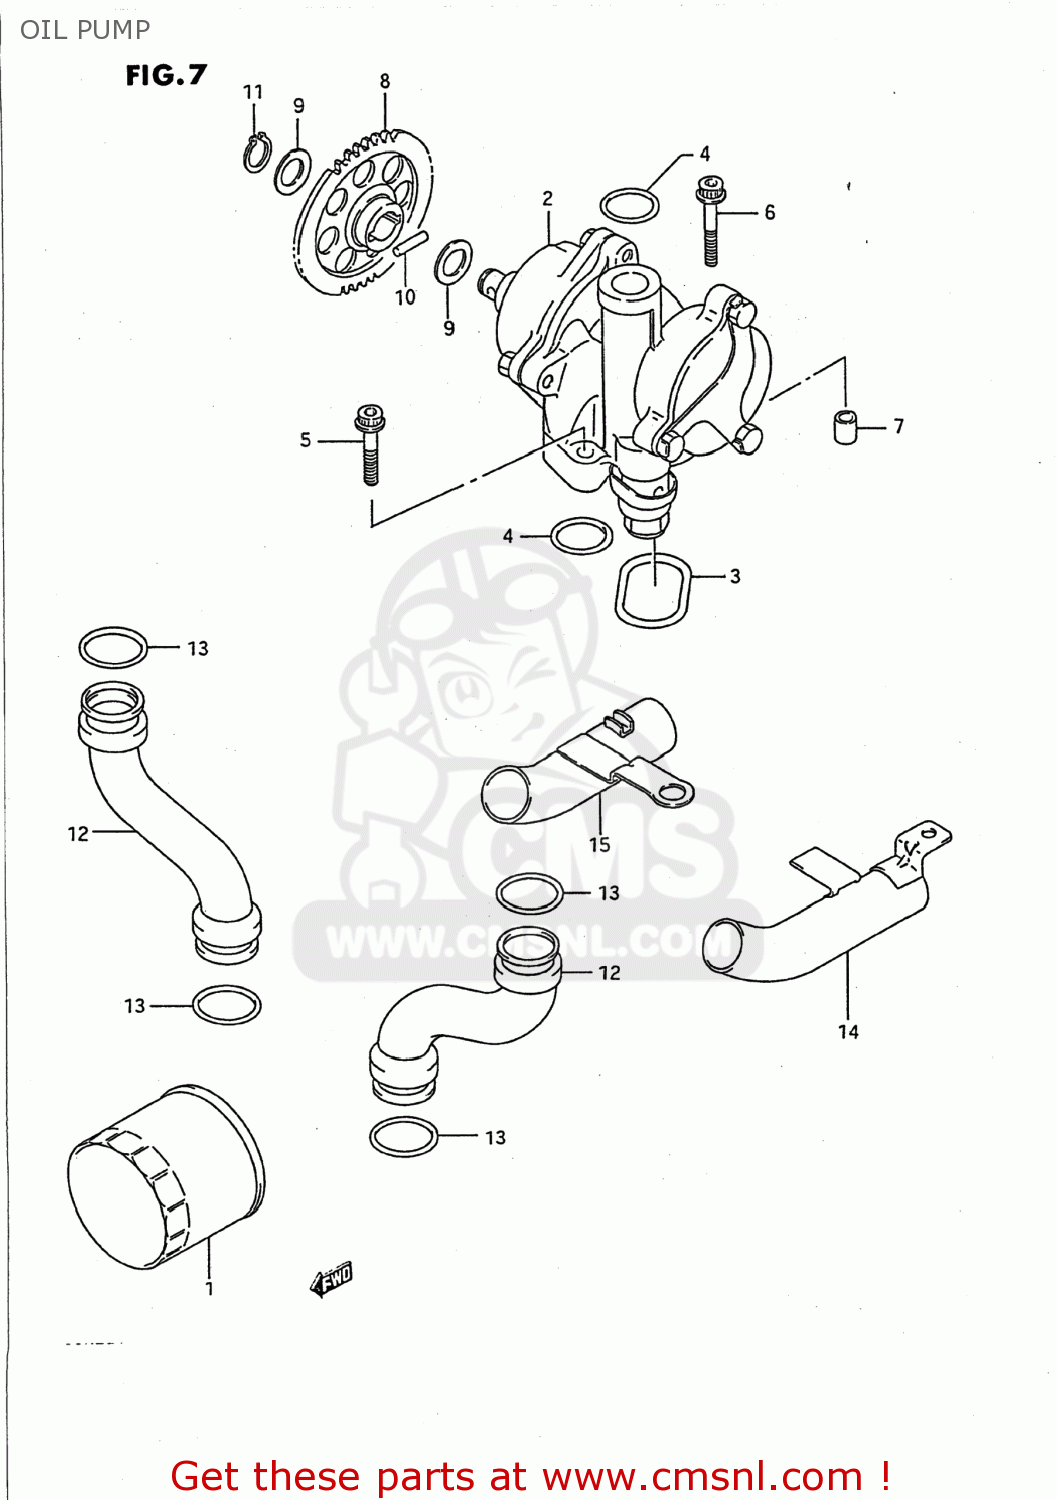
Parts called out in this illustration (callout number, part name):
1	FILTER,OIL
2	PUMP ASSY,OIL
3	O RING,OIL PUMP
4	O RING(D:3.2,ID:17.8)
5	BOLT
6	BOLT
7	PIN
8	GEAR,OIL PUMP DRIVEN
9	SHIM
10	PIN(5X18)
11	CIRCLIP,12 MM
12	PIPE,OIL OUTLET
13	O RING(D:3.7,ID:21.7)
14	PIPE,OIL OUTLET UNDER,L
15	PIPE,OIL OUTLET UNDER,R
